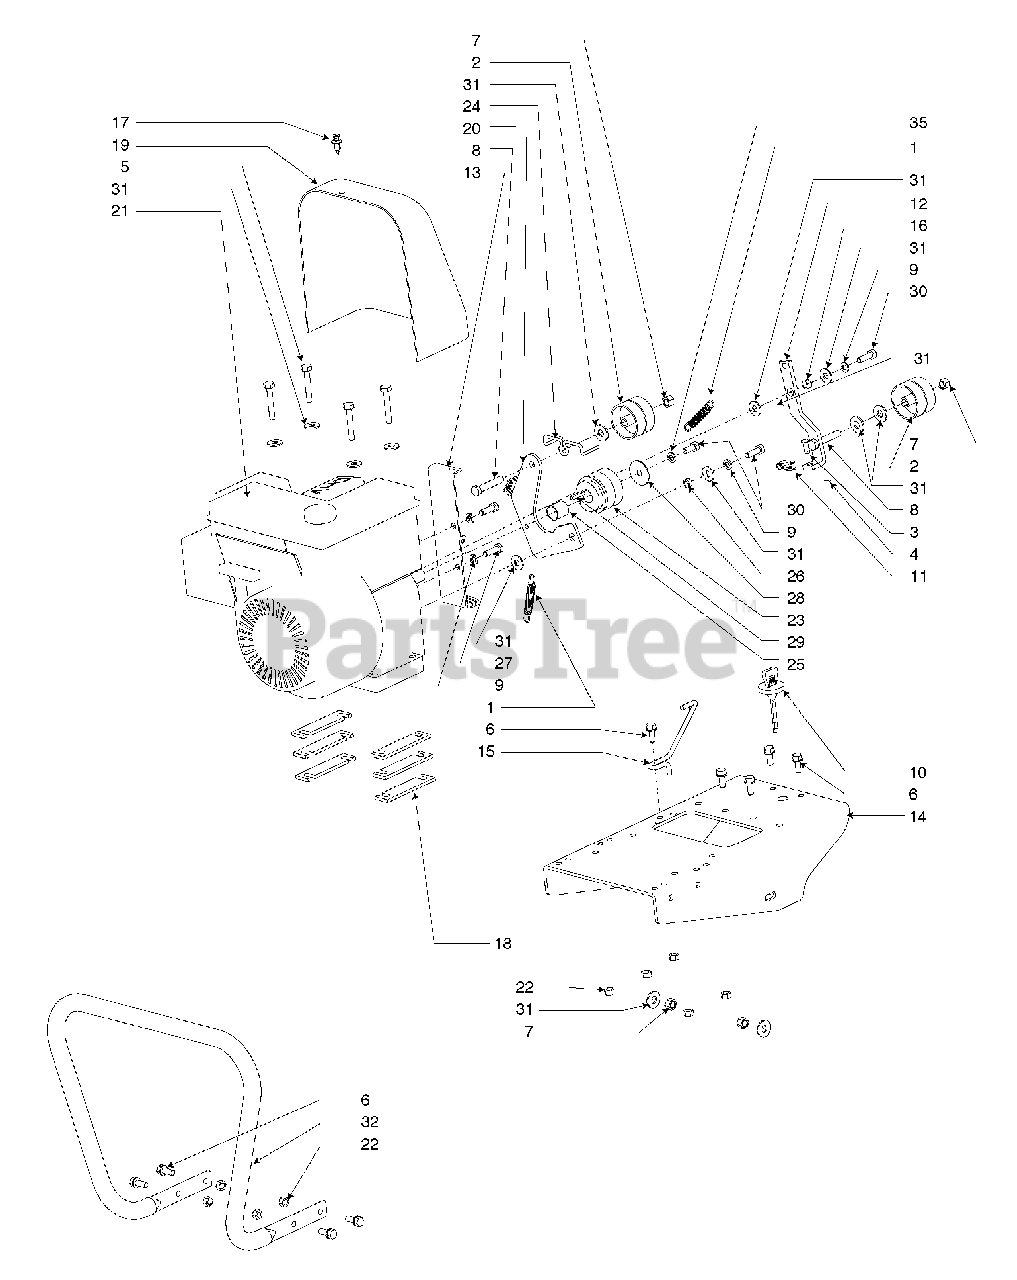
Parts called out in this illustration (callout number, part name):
1	SPRING, Forward Arm
2	PULLEY, Idler, Forward
3	PIN, Clevis
4	PIN, Cotter, 5/64 x 1/2
5	BOLT, Hex-Head Capscrew, 5/16-18 x 2
6	BOLT, Hex-Flange Head, 5/16-18 x 3/4
7	NUT, Hex, Locking, Two-Way, 3/8-16
8	BOLT, 3/8-16 x 2
9	WASHER, Locking, Spring, 5/16
10	DIP STICK
11	YOKE, Clevis, Zinc-Plated
12	ARM, Forward
13	CABLE PULL ASSEMBLY
14	MOUNT, Motor
15	GUIDE, Belt
16	BUSHING, Forward Arm
17	RIVET, Push-In, Plastic
18	SHIM, Engine Weight Block
19	GUARD, Belt
20	REVERSE TINE ASSEMBLY
21	* ENGINE, 8TP Briggs & Stratton INTEK
22	NUT, Bi-Way Lock, 5/16-18
23	PULLEY, Two-Groove, 3/4
24	GUIDE, Belt, Reverse
25	SPACER, Drive Pulley, 9/16
26	BUSHING, Reverse Arm
27	BOLT, 5/16-24 x 3/4
28	WASHER, 5/16 x 1-1/2
29	KEY, 3/16 x 1
30	BOLT, 5/16-24 x 1
31	WASHER, Flat, 5/16
32	GUARD, Bumber
35	WASHER, Flat 11/16 ID X 1-1/4 OD
